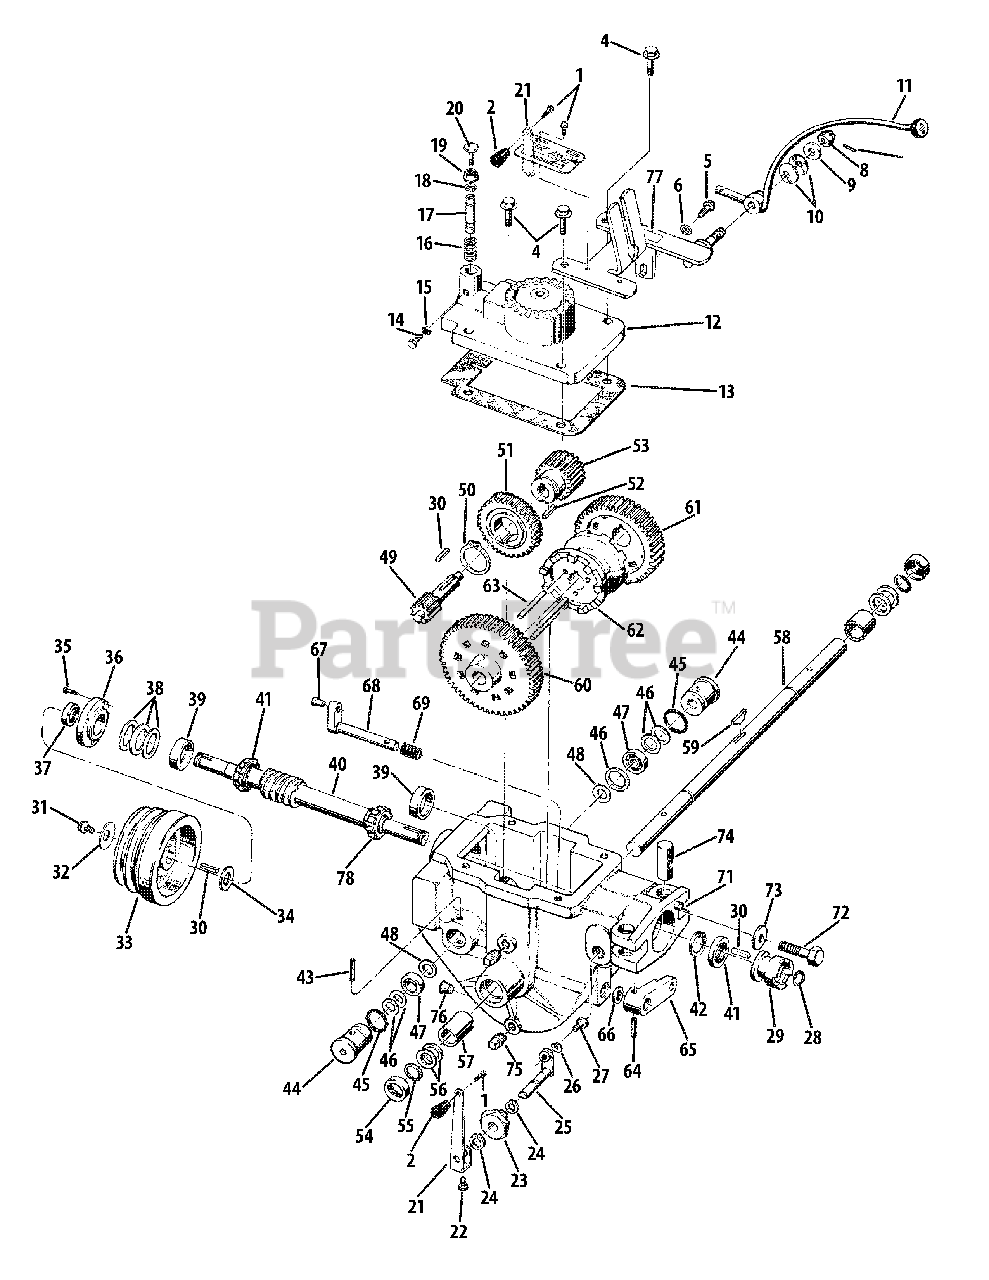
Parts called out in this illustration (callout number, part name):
1	Hex Bolt, #10-32 x 3/8 "
3	Plate
4	Hex Flange Bolt, 3/8-16 x 1-1/2"
5	Hex Flange Bolt, 5/16-18 x 3/4"
6	Flat Washer, 5/16"
7	Spring Pin, 1/8 "
8	Hex Nut, 1/2-20
9	Shoulder Washer, 1/2"
10	Disc Spring Washer
11	Wheel Speed Shift Lever
12	Power Unit Transmission Cover
13	Transmission Cover Gasket
14	Hex Bolt, 5/16-18 x 1"
15	Hex Nut, 5/16"-18
16	Plunger Spring
17	Plunger
18	Clip Ring
19	Flange Lock Nut
20	Hex Bolt, 3/8 -16x1-1/2"
21	Tines/PTO Clutch Lever
22	Hex Bolt, 1/4-20 x 1/2"
23	Tines/PTO Clutch Bushing
24	External Retaining Ring
25	Tines/PTO Clutch Shaft
26	Hi-Collar Lockwasher, 1/4"
27	Socket Head Screw, 1/4-20 x 3/8"
28	External Retaining Ring
29	Dog Clutch
30	Key, 3/16 x 1"
31	Hex Bolt, 5/16-24 x 3/4"
32	Spring Washer, .827 x .331 x .098
33	Transmission Drive Pulley
34	Flat Washer, 1-1/4"
35	Flange Nut, 1/4-20 x .75
36	Front Bearing Cap
37	Oil Seal
38	Flat Washer, 1.175 x 1.5 x .062
38	Flat Washer, 1.175 x 1.5 x .005
38	Flat Washer, 1.175 x 1.5 x .03
38	Flat Washer, 1.175 x 1.5 x .01
39	Cup Bearing
40	Main Drive Shaft
41	Oil Seal
42	Retaining Ring
43	Roll Pin (Spirol), 1/4 x 2
44	Pinion Bearing
46	Flat Washer, 1.234 x 1.015 x .062
46	Flat Washer, 1.234 x 1.015 x .033
46	Flat Washer, 1.234 x 1.015 x .01
47	Pinion Shaft
48	Washer
49	Pinion Stem
50	External Retaining Ring
51	Worm Gear
52	Key, 3/16" x 5/8 "
53	Fast Speed Pinion Gear
54	Oil Seal
55	External Retaining Ring
56	Flat Washer, 1.375 x 1.015 x .005
56	Flat Washer, 1.375 x 1.015 x .01
56	Flat Washer, 1.375 x 1.015 x .015
56	Flat Washer, 1.375 x 1.015 x .03
56	Flat Washer, 1.375 x 1.015 x .062
57	Bushing, 1.25 x 1.005 x 1.5
58	Wheel Shaft
59	Hi-Pro Key, .250 x 1.8125
60	Slow Speed Gear
61	Faste Gear Speed
62	Dog Clutch
63	Clutch Guide Pin, 1/4"
64	Roll Pin, 3/16" x 1-1/4"
66	Oil Seal
67	Wheel Speed Shifting Pin
68	Wheel Speed Shifting Shaft
70	Transmission Housing
71	Alignment Pin
72	Hex Bolt, 1/2-13 x 2"
73	Disc Spring Washer
75	Pipe Plug, 1/4"
76	Plug-Red Plastic
77	Clutch Bracket
78	Cone Bearing
